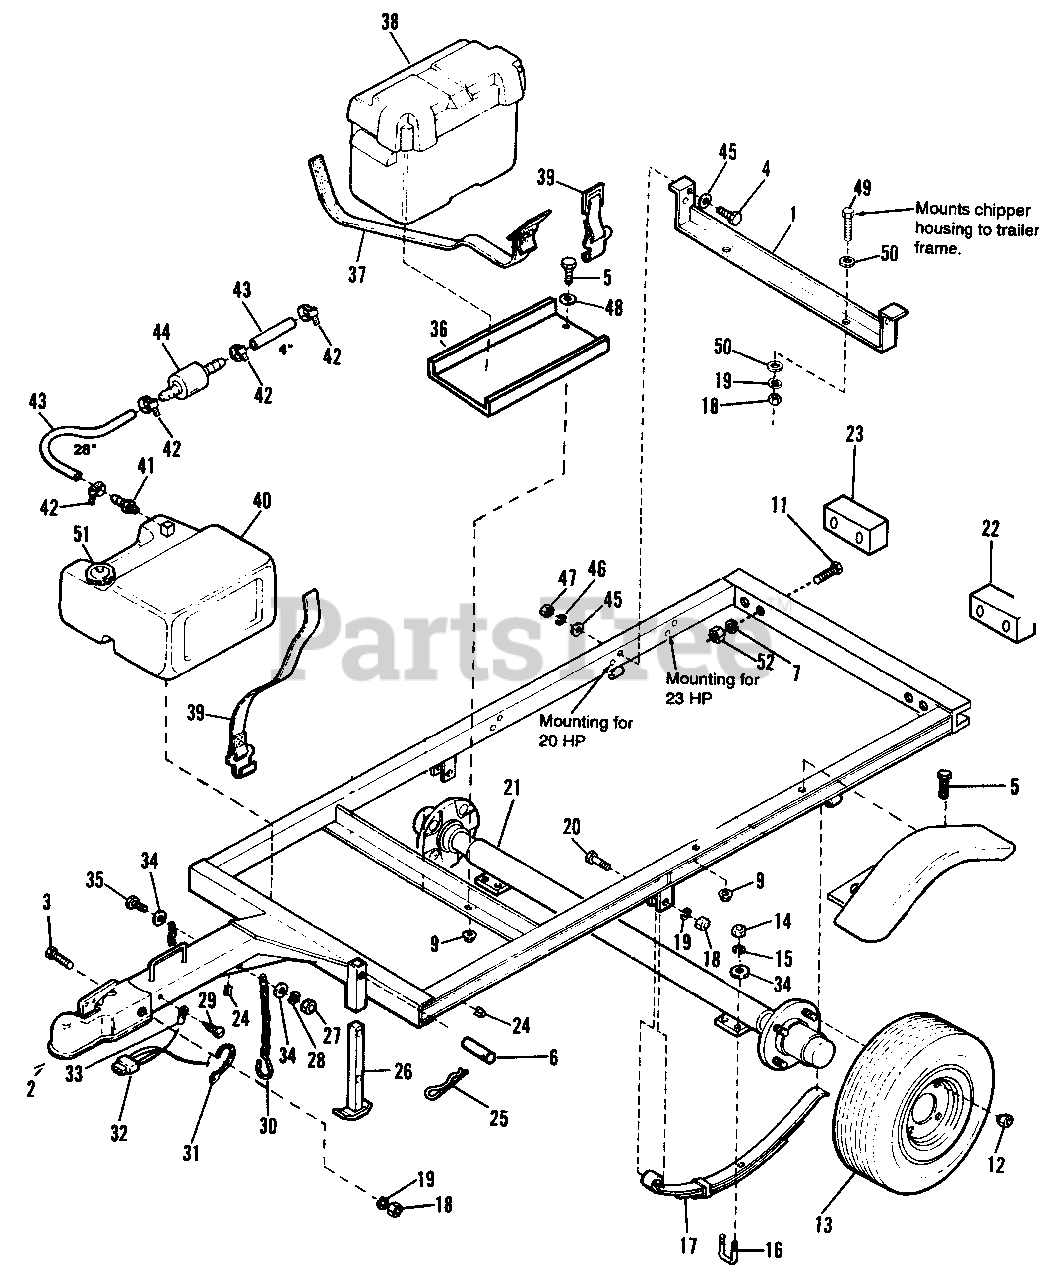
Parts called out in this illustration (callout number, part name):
1	BRACKET, Mounting
2	COUPLER, Trailer, 2" Ball
3	CAPSCREW, Hex, 1/2-13 x 4
4	CAPSCREW, 7/16-14 x 1-1/4
5	CAPSCREW, Hex Hd., 5/16-18 x 3/4
6	PIN, Clevis
7	LOCKWASHER, 1/4
8	TRAILER ASSEMBLY
9	NUT, Whiz Lock, 5/16-18
10	FENDER, Round
11	WASHER, Fender, 5/16 x 1-1/4 O.D.
13	WHEEL & TIRE ASSY., 5.70 x 8
14	NUT, Hex, Center Lock, 3/8-16
15	LOCKWASHER, 3/8
16	U-BOLT, 3/8-16
17	LEAF SPRING
18	NUT, Hex, 1/2-13
19	LOCKWASHER, 1/2
20	CAPSCREW, 1/2-13 x 3
21	AXLE ASSEMBLY
22	TAILLAMP ASSY., L.H.
23	TAILLAMP ASSY., R.H.
24	CLAMP, Cable
25	CLIP, Hairpin
26	JACK ASSEMBLY
27	NUT, Hex, 3/8-16
28	LOCKWASHER, 3/8
29	SCREW, Taptite, 1/4-20 x 3/8
30	SAFETY CHAIN
31	TIE, Wire, 4"
32	HARNESS, Wiring, 117-1/2
33	TONGUE, Nylon Ring
34	WASHER, 3/8
35	CAPSCREW, 3/8-16 x 1-1/2
36	TRAY, Battery
38	CASE, Battery (includes Ref. No. 37)
39	Tie Down, Gas Tank
40	TANK, Gas, 6 Gal. (Incl. Ref. No. 51)
41	FITTING, Male, Nylon, 1/4
42	CLAMP, Hose
43	FUEL LINE, 1/4 (4" & 17" Sections)
46	LOCKWASHER, 7/16
47	NUT, Hex, 7/16-14
48	WASHER, 5/16
49	CAPSCREW, Hex, 1/2-13 x 1-1/2
50	WASHER, Flat, 1/2
52	NUT, Hex, 1/4-20
